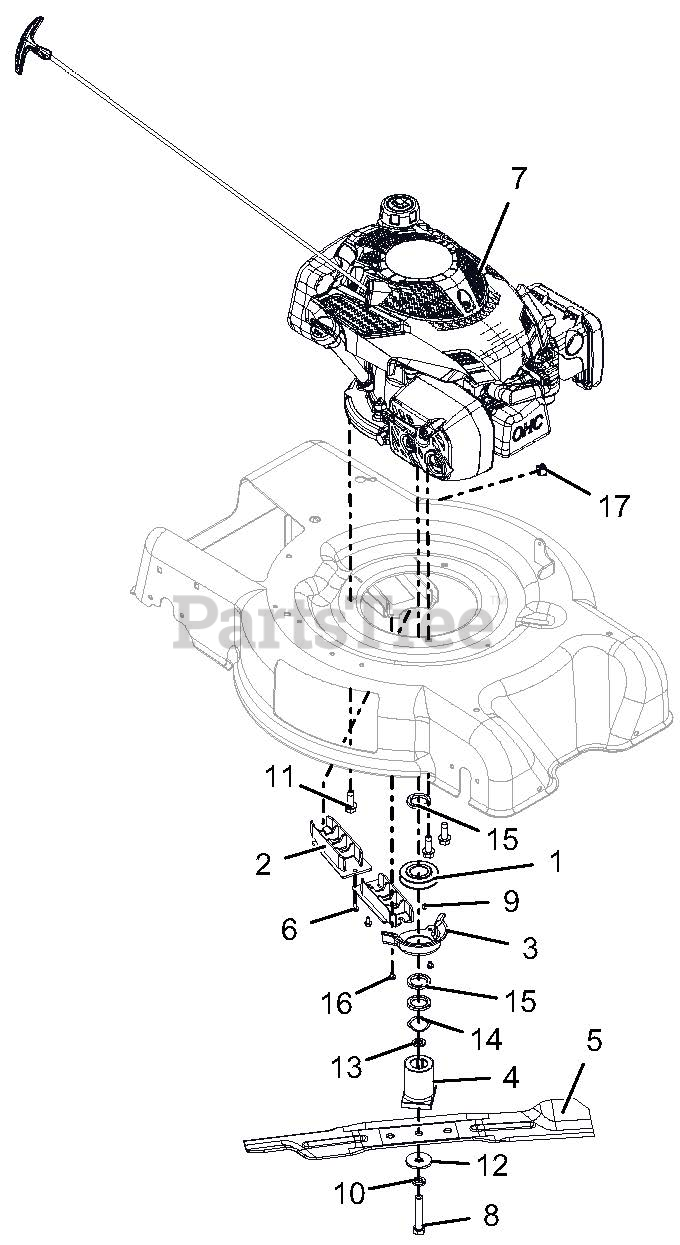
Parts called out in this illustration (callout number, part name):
1	PULLEY, MACHINED POWDER METAL
2	GUIDE, BELT INNER
3	GUIDE, BELT CRANKSHAFT
4	ADAPTOR, BLADE
5	BLADE, MOWER 21" HIGH-LIFT
6	SCR, TAP 10-24X.375 PRE-COAT 80
7	ENGINE, SUBARU 175CC VERT ES
8	BLT-HEX .44-20X2.25 GR8 YWZC
9	KEY-SQ .188X.188X.250
10	WSHR-LK .44X.109 REG YWZC
11	SCR-TAP .38-16X1.00 HWH TR YZ
12	WSHR-FL-STL .4375X1.50X.125 YWZC
13	WSHR-FL-STL .459X.750X.105 YWZC
14	WASHER, WAVE
15	SPCR, 1.00 X 1.375 X .179
16	SCR-TAP 10-24X.25 CRSLPH TR YZ
17	PLUG, DOME-BLACK, .625 DIA
